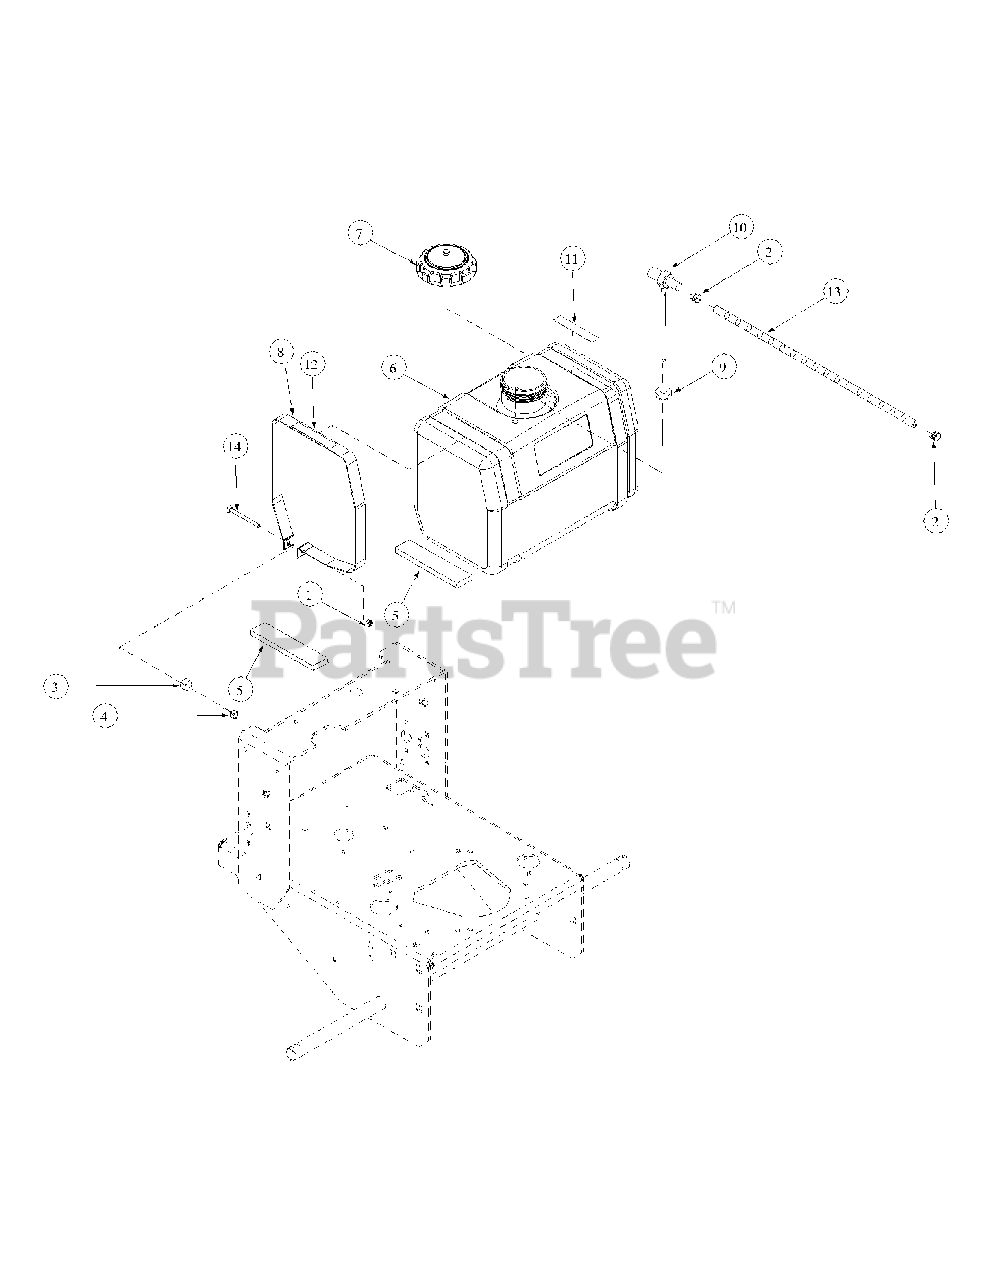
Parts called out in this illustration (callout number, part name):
1	Lock Nut, Nylon Insert, 1/4-20
2	Uni-Clamp
4	Nut, 1/4-20
5	Rubber Stop Pad
6	Fuel Tank
7	Fuel Cap, 3.5
8	Fuel Tank Strap
9	Grommet Fuel Tank
10	Shut Off Fuel Tank
11	Label, Mower Warning Turn Off Engine
12	Label, Mower Instruction, Fuel Valve
13	Hose Fuel, 22" x .25 ID
14	Carriage Bolt, 1/4-20 x 3.00
